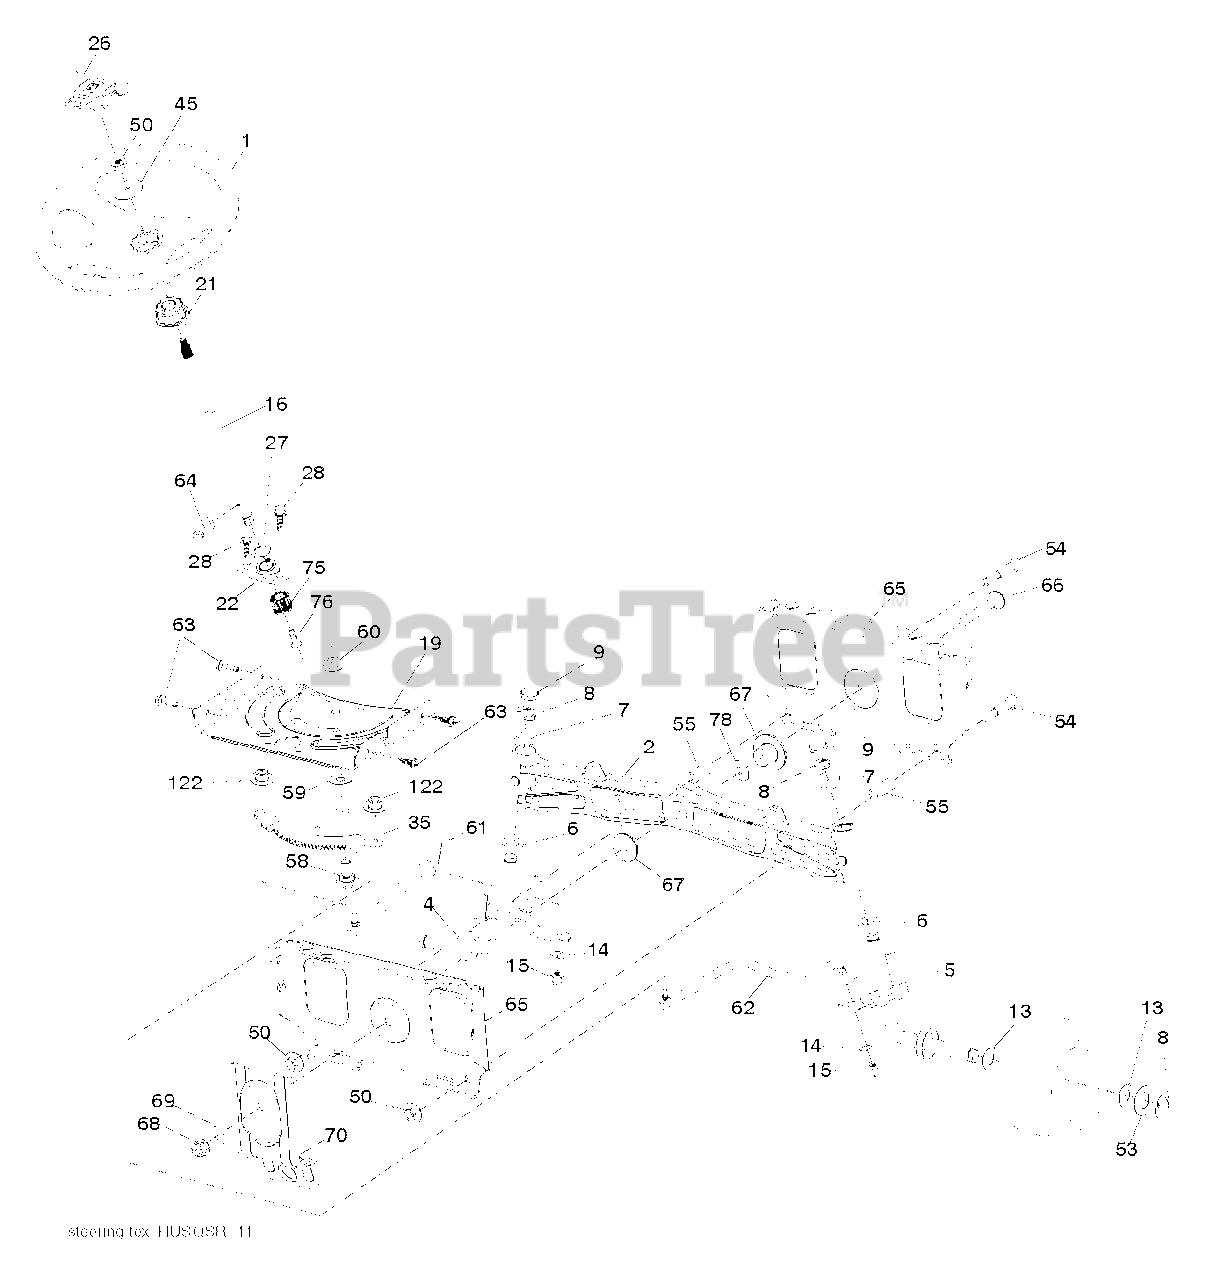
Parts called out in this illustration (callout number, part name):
1	WHEEL.STEER.HUSQ.SR.498.OVMLD
2	AXLE.CAST.IRON
4	SPINDLE.WELDED.LH.16"TEX
5	SPINDLE.WELDED.RH.16"TEX
6	THRUST WASHER
9	CAP.SPINDLE.BLACK
14	SLW 3/8 STD
15	NUT CROWNLOCK 3/8-24
16	SHAFT.STEER.2HIGH.SPLND.PLATED
19	PLATE.STEER.DDL.NLT/NG
21	ADAPTER.WHEEL.STEER.SPLND.ALUM
22	BEARING.SHAFT.STEER.LOWER.625
26	INSERT.CAP.WHL.STRG.HUSQ.PREM
28	SCREW, 3/8-16X3/4
35	GEAR.SECTOR.PLATE.DDL.
45	WASHER.3/8ID.2-3/8OD.12GA.PLTD
50	NUT LOCK FLG 3/8-16 UNC
53	WASHER.HARDENED
55	SPACER.BRACE.AXLE
58	BOLT.SHOULDER.SECTOR.P
59	WASHER.THURST.SECTOR.S
60	NUT FLANGE LOCK 5/8-11
61	DRAGLINK.LH.BALLSTUD.D
62	DRAGLINK.RH.BALLSTUD.D
63	SCREW
64	RETAINER.CLIP.SPRING.S
65	BRACE.AXLE.FRONT.NLT/N
66	BOLT HEX FGHD 7/16-14 X 3 SERR
67	BUSHING.PM.FRONT AXLE
68	NUT.LOCK.FLANGE.7/16
69	WASHER.1.5X.505X.118
70	BRACKET.FRT.DECK.SUSP.RR.MT431
75	PINION.ZINC PLATED
76	SCREW HEAD SOCKET LRVB
78	THRUST WASHER
122	CAP.GEAR.SECTOR.TEX
